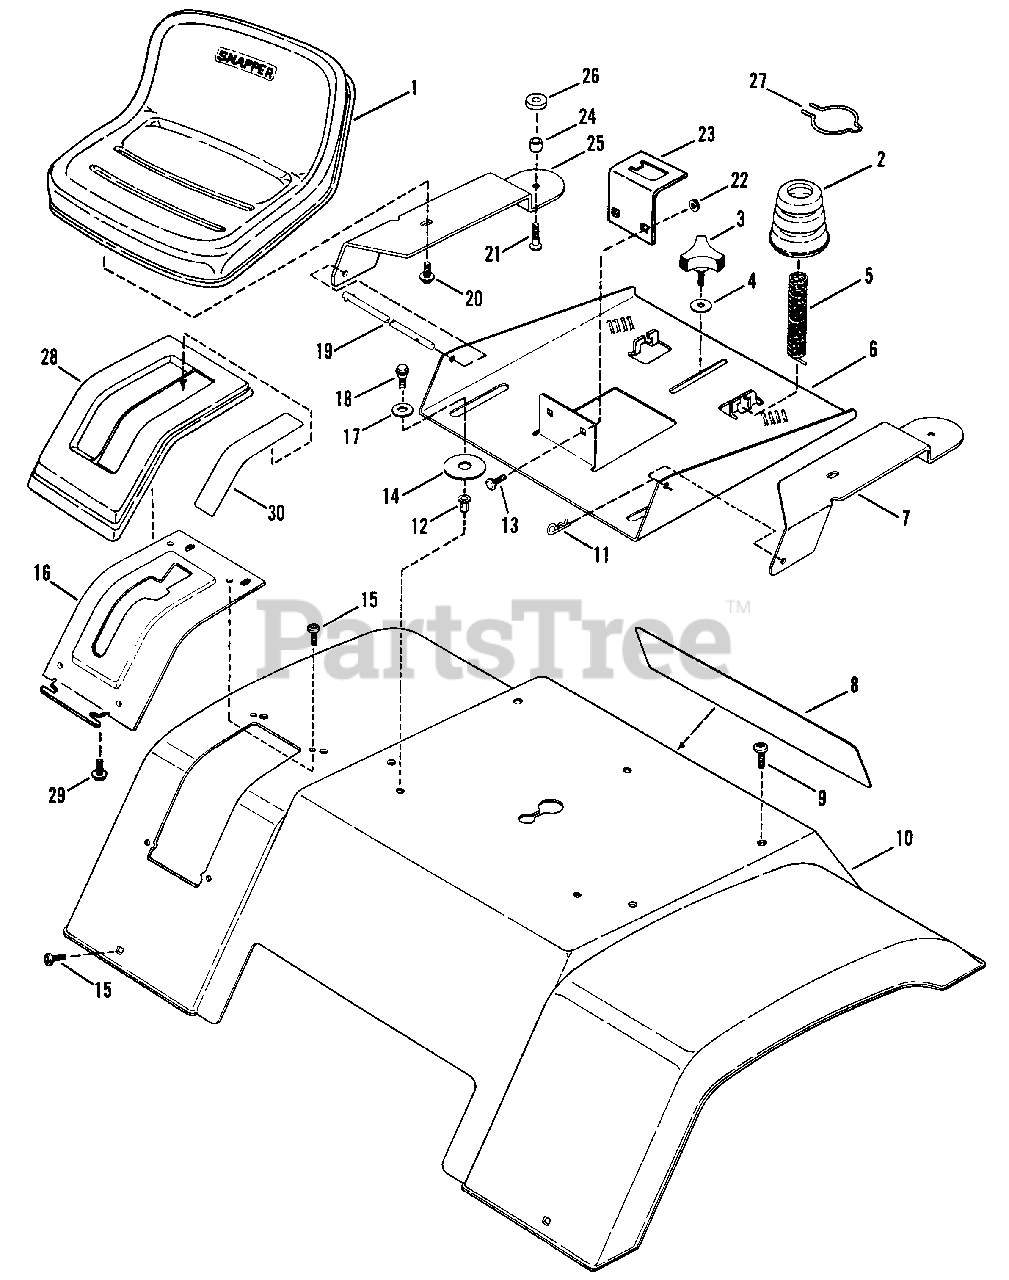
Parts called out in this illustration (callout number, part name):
1	SEAT, Operator's
2	CUSHION, Seat
3	KNOB, 3 Prong 5/16-18 x 3/4
4	WASHER 5/16"
5	SPRING
6	SUPPORT, Seat
7	BRACKET, Seat Support, L.H.
8	DECAL, SNAPPER Molded Logo
9	SCREW, 5/16-18x7/8" Torx. Hd., S.T.
10	FENDER, Rear
11	PIN, Hair 1.12"
12	RIV-NUT, 5/16-18
13	BOLT, 5/16-18x5/8" Short Neck Carriage
14	SPACER, WEAR Nylon 2.0 x .62 x .055
15	SCREW, 1/4-20x5/8" Torx Hd., Self-Tapping
16	DETENT, Shift
17	WASHER, Flat .445 x 1.0 x .059
18	SCREW, Shoulder, 5/16-18x3/4"
19	ROD, Seat Hinge
20	BOLT, 5/16-18x1/2" Hex Flange Lock
21	SCREW, 5/16cx1" Flat Hd. Hex Recess
22	NUT, 5/16-18 Hex Flange Lock
23	BRACKET, Switch
24	SPACER, .39 x .375 (No longer available)
25	BRACKET, Seat Support, R.H.
26	WASHER, Flat .406X1.38X.25 BZ
27	CLIP, Seat Bumper
28	COVER, Shift Detent
29	SCREW, #10-16x1/2" Self-Tapping
30	DECAL, Shift Cover
